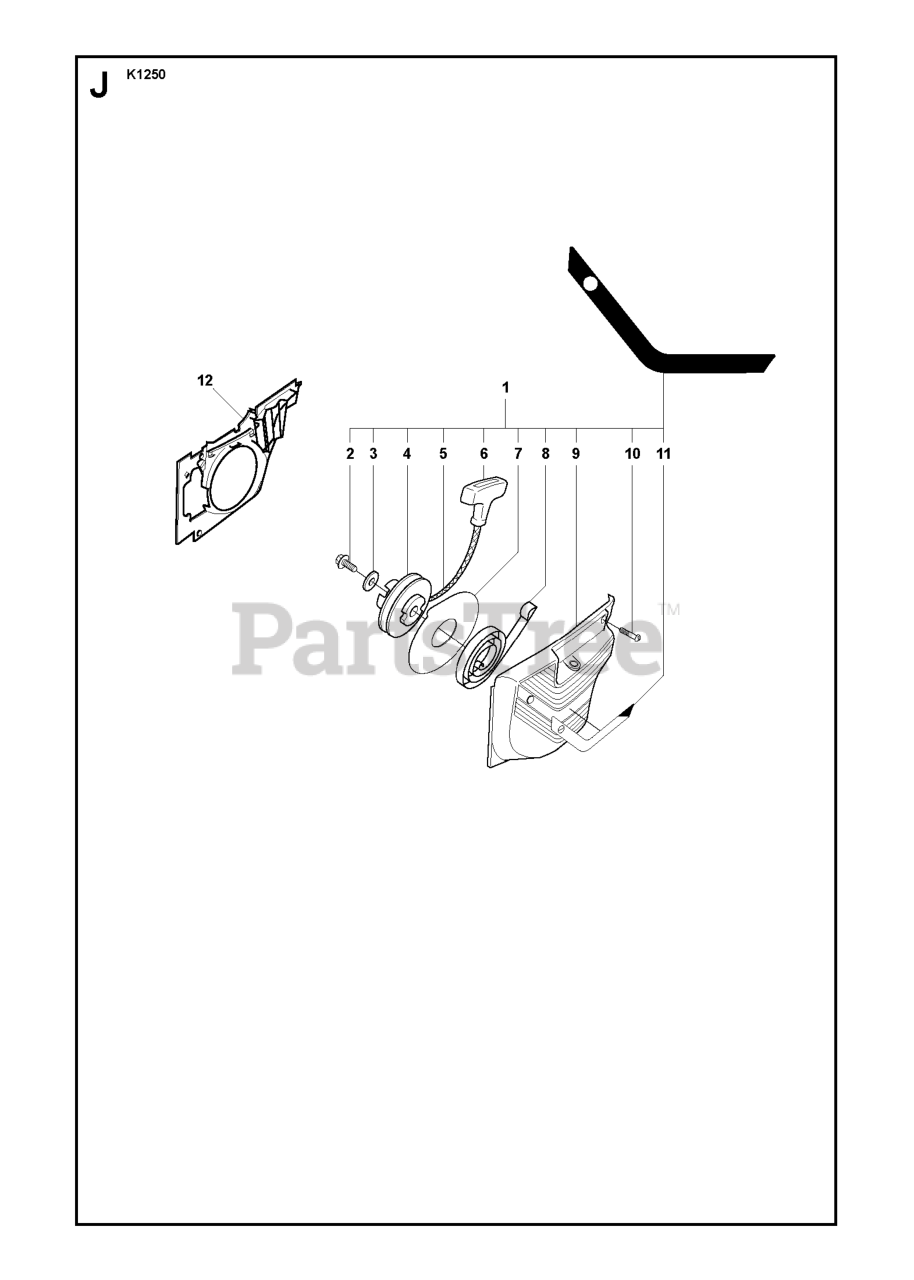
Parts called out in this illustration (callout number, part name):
1	STARTER
2	SCREW
5	STARTER ROPE
6	STARTER HANDLE
8	RECOIL SPRING
9	STARTER COVER
10	SCREW
12	AIR CONDUCTOR
